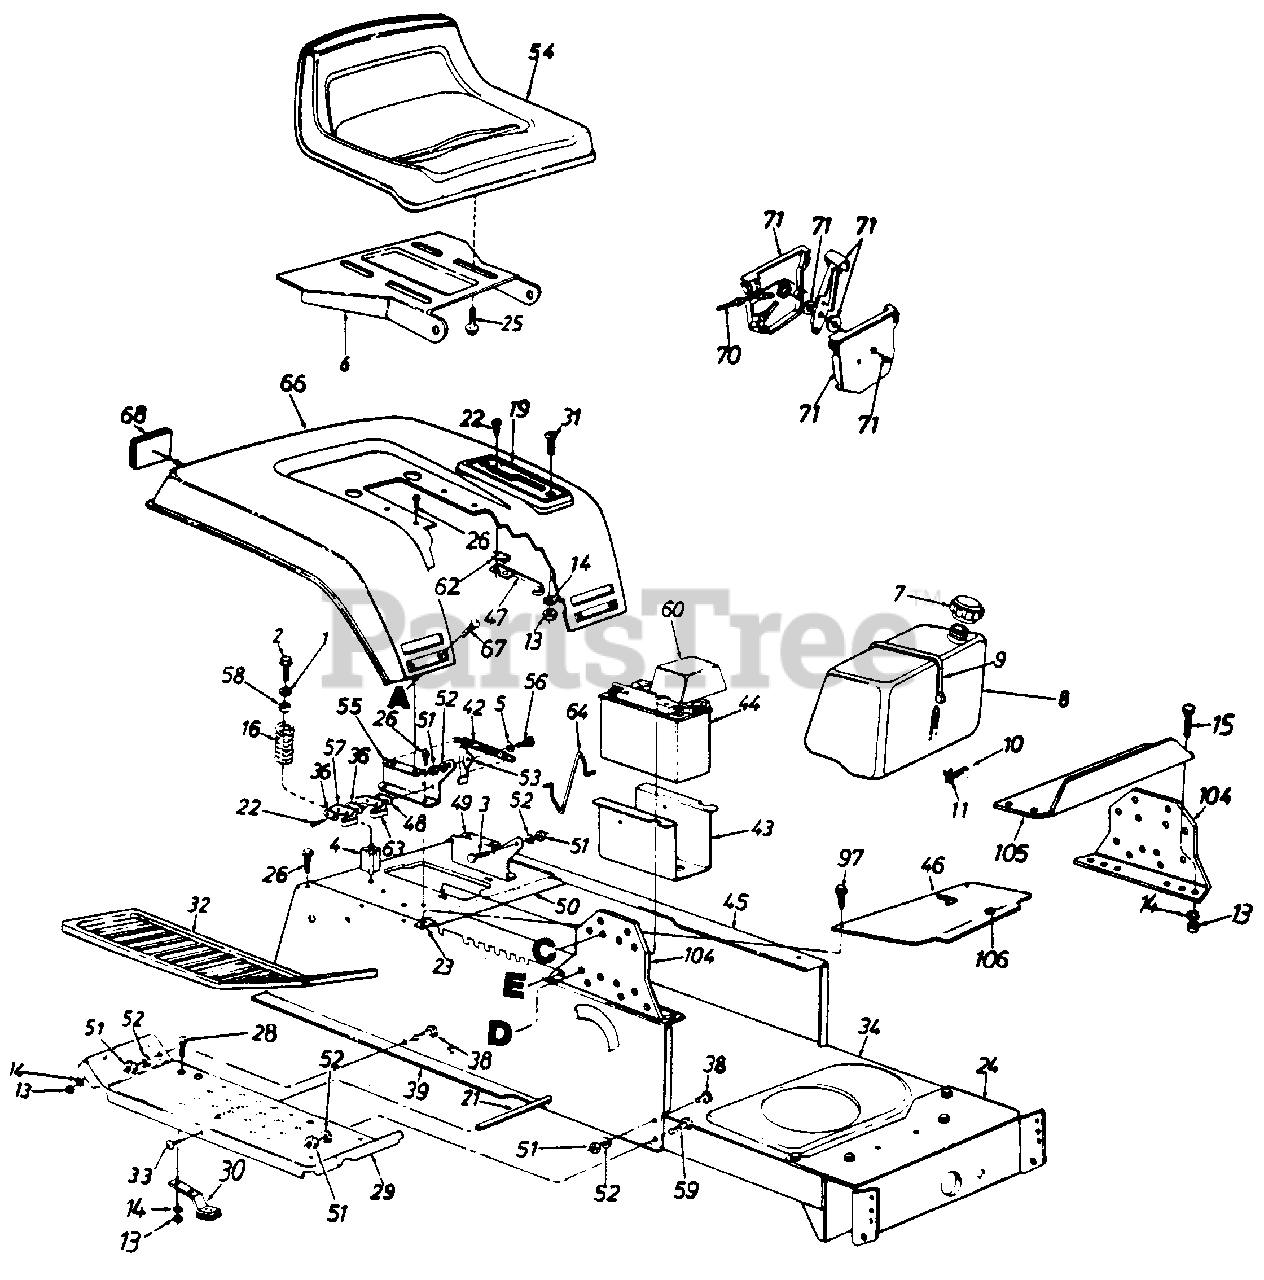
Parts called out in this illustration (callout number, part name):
1	Fl-Wash. .344" l.D. x .875"
2	Hex Wash. Hd. Tap Scr. 5/16-18 x 3.25" Lg.
3	Shld. Bolt .437" Dia. x .162"
4	Spring Spacer
5	Spr-Wash. .445" l.D. x .75
6	Seat Pivot Bracket
7	Fuel Cap w/o Gasket
8	Fuel Tank
9	Tie Strap
10	Fuel Line
13	Hex Nut 1/4-20 Thd.
14	L-Wash. 1/4" l.D.
15	Hex Bolt 1/4-20 x .62" Lg.
16	Compression Spring
19	Speed Control Index Brkt.
21	Running Board Rod
22	Hex Wash. Hd. AB-Tap Scr. #8 x .50" Lg.
23	Speed Nut #10Z
24	Front Pivot Brkt.
25	Hex Tap Scr. 3/8-16 x .75"
26	Hex Wash. Hd. AB-Tap Scr. 5/16 x .75" Lg.
28	Carriage Bolt 1/4-20 x .62"
29	Running Board
30	Blade Brake Ass'y.
31	Truss Mach. Scr. 1/4-20 x ,75" Lg.
32	Rubber Foot Pad-L.H.
33	Truss Mach. Scr. 5/16-18 x .75" Lg.
34	Lower Frame
36	Insulator Plate
38	Hex Bolt 5/16-18 x .75" Lg.
39	483/N Upper Frame-R.H.
42	Extension Spring 5.31" Lg.
43	Battery Tray
44	12-V BaKery
45	483/N Upper Frame-L.H.
46	Shift Cover
47	Reverse Safety Switch
48	Insulator Boss Plate
52	L-Wash. 5/16n l.D.
53	Seat Lift Brkt.
56	Shld. Bolt .437" Dia. x .268"
57	Spring Switch
59	Hex Wash. Hd. Scr. 5/16-18 x .87" Lg
60	BaKery Cover
62	Insulator Nut Plate
63	Safety Switch
64	BaKery Tray Clip
68	Reflector
70	ThroKle Wire
71	ThroKle Control Box Ass'y.
97	Truss Mach. B-Tap Scr. #10 x 5" Lg.
106	Snap Bushing
